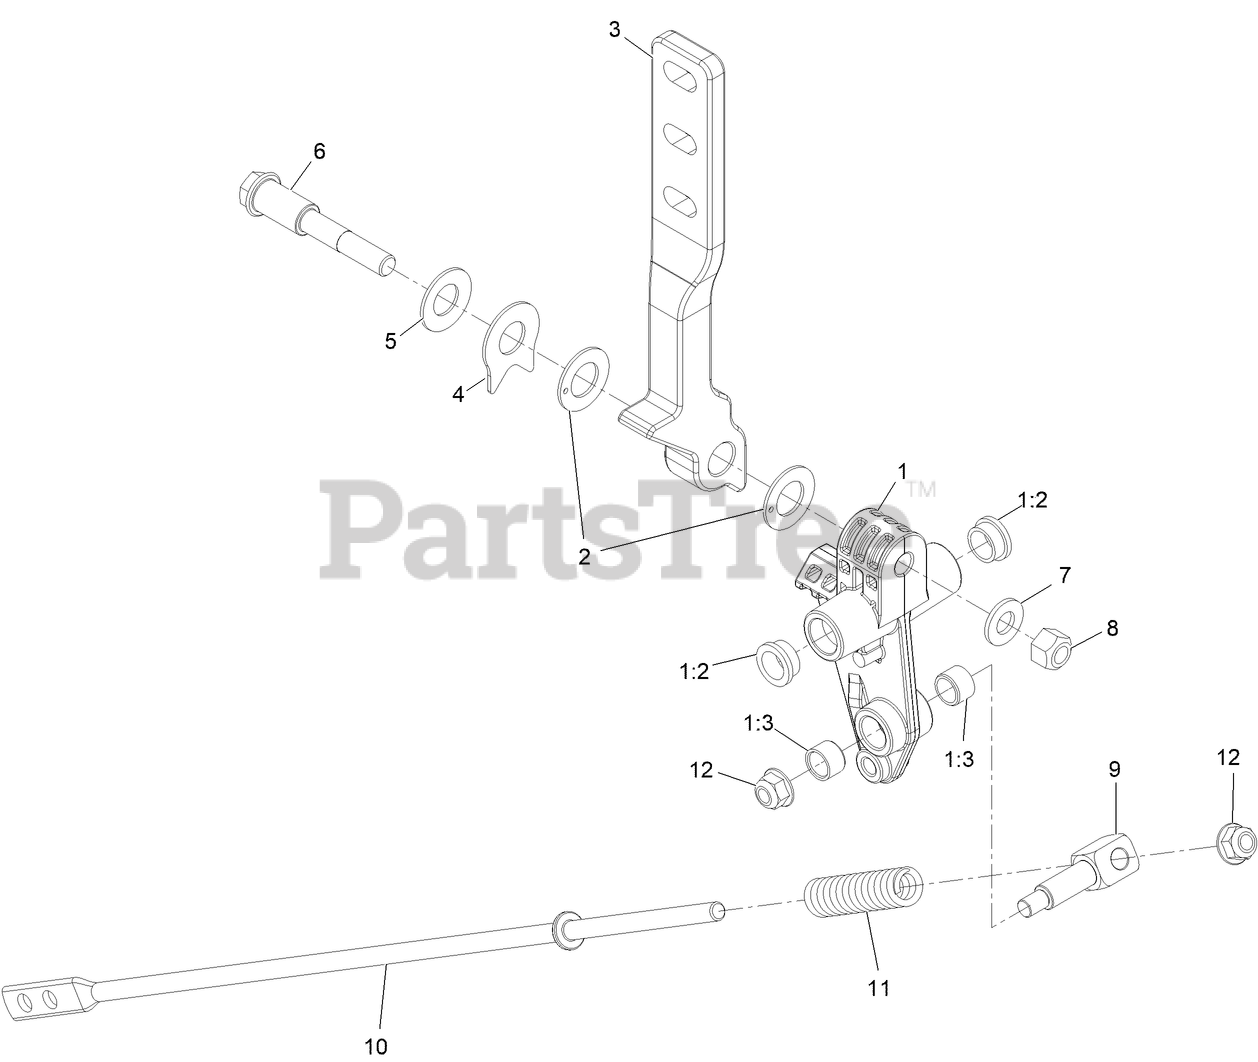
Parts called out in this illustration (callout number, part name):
1	CONTROL ARM ASM
1:2	BUSHING
1:3	BUSHING-SLEEVE
2	WASHER-FRICTION
3	Lever, Motion Control
4	Spacer, Anti-Rotation
5	WASHER-BELLEVILLE
6	Bolt-Pivot
7	WASHER-FLAT
8	NUT-LOCK, CONE
10	Link, Motion Control
11	Spring, Compression
12	NUT-HF, NI
